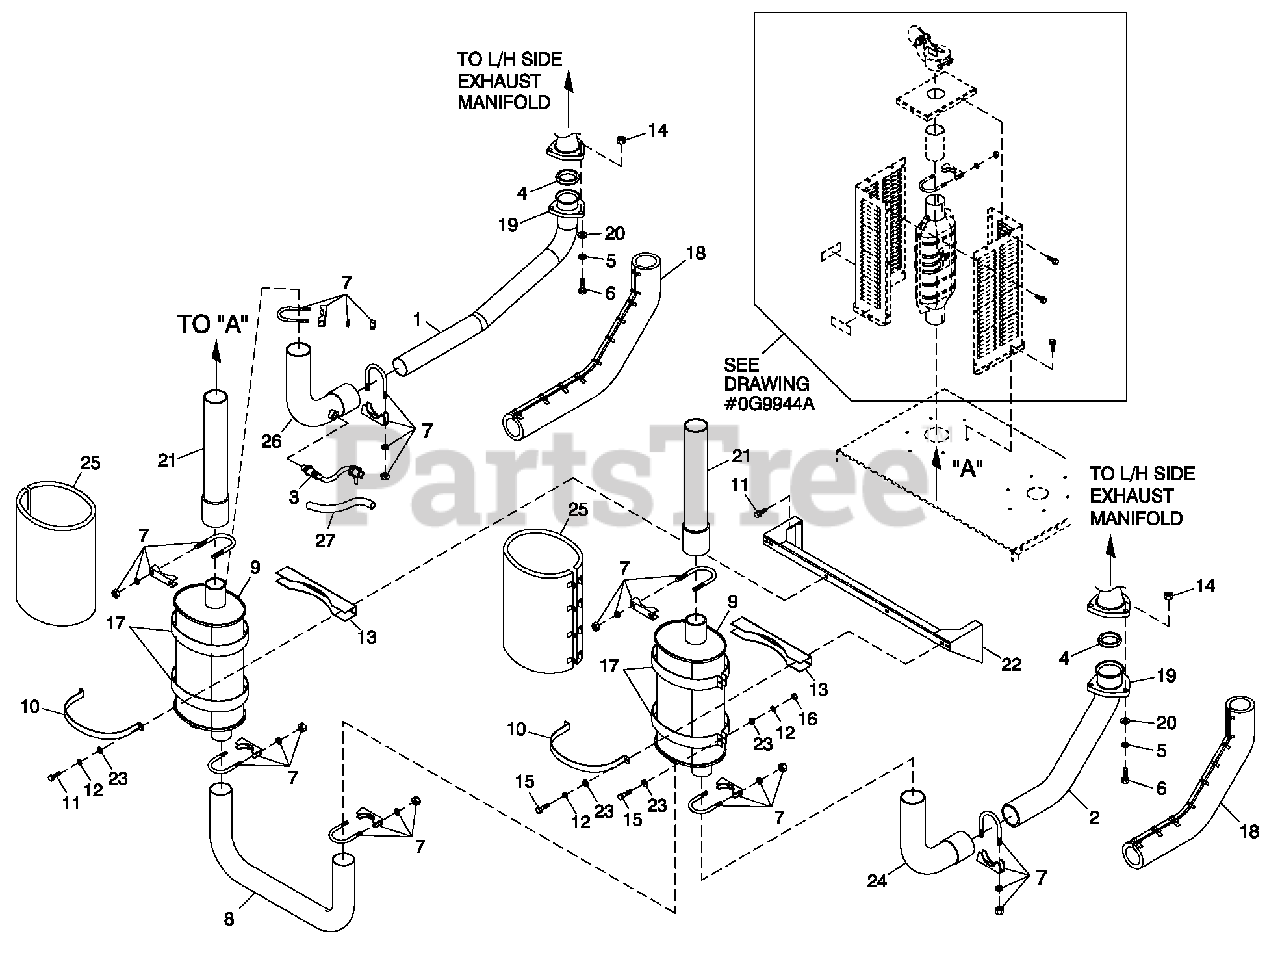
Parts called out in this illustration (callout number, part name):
1	PIPE EXH MAN R/H 6/8 G/BCPLEPA
2	PIPE EXH MAN L/H 6.8L G/B CPL
3	SENSOR OXYGEN
4	RING GASKET 2.5 DIA
5	WASHER LOCK M10SS
6	SCREW HHC M10-1.5 X 50 SS FTH
7	BOLT U 3/8-16X2.62
8	PIPE EXHAUST CROSSOVER
9	MFLR 7" X 9" X 25" (2) 2.5" IN/2.5" OUT
10	MUFFLER STRAP
11	SCREW THF M6-1 X 16 N WA Z/JS
12	WASHER LOCK M6-1/4
13	MUFFLER BRACKET STIFFENER
14	NUTHEXM10-1.5SS
15	SCREW HHC M6-1.0 X 35 G8.8 BLK
16	NUT HEX M6X 1.0 G8YEL CHR
17	MUFFLER STRAP UPPER/LOWER
18	EXHAUST BLANKET 900MM LONG
19	FLANGE EXHAUST
20	WASHER FLAT 3/8 SS
21	EXHUAST OUTLET PIPE CPL
22	BRKT MUFFLER
23	WASHER FLAT 1/4-M6 ZINC
24	PIPE ELBOW EXHAUST MUFFLER
25	BLANKET EXHAUST MUFFLER 584MM
26	PIPE ELBOW EXHAUST O2 SENSOR
27	REFLEX WRAP 13MM 13X 460 (12"LG)
